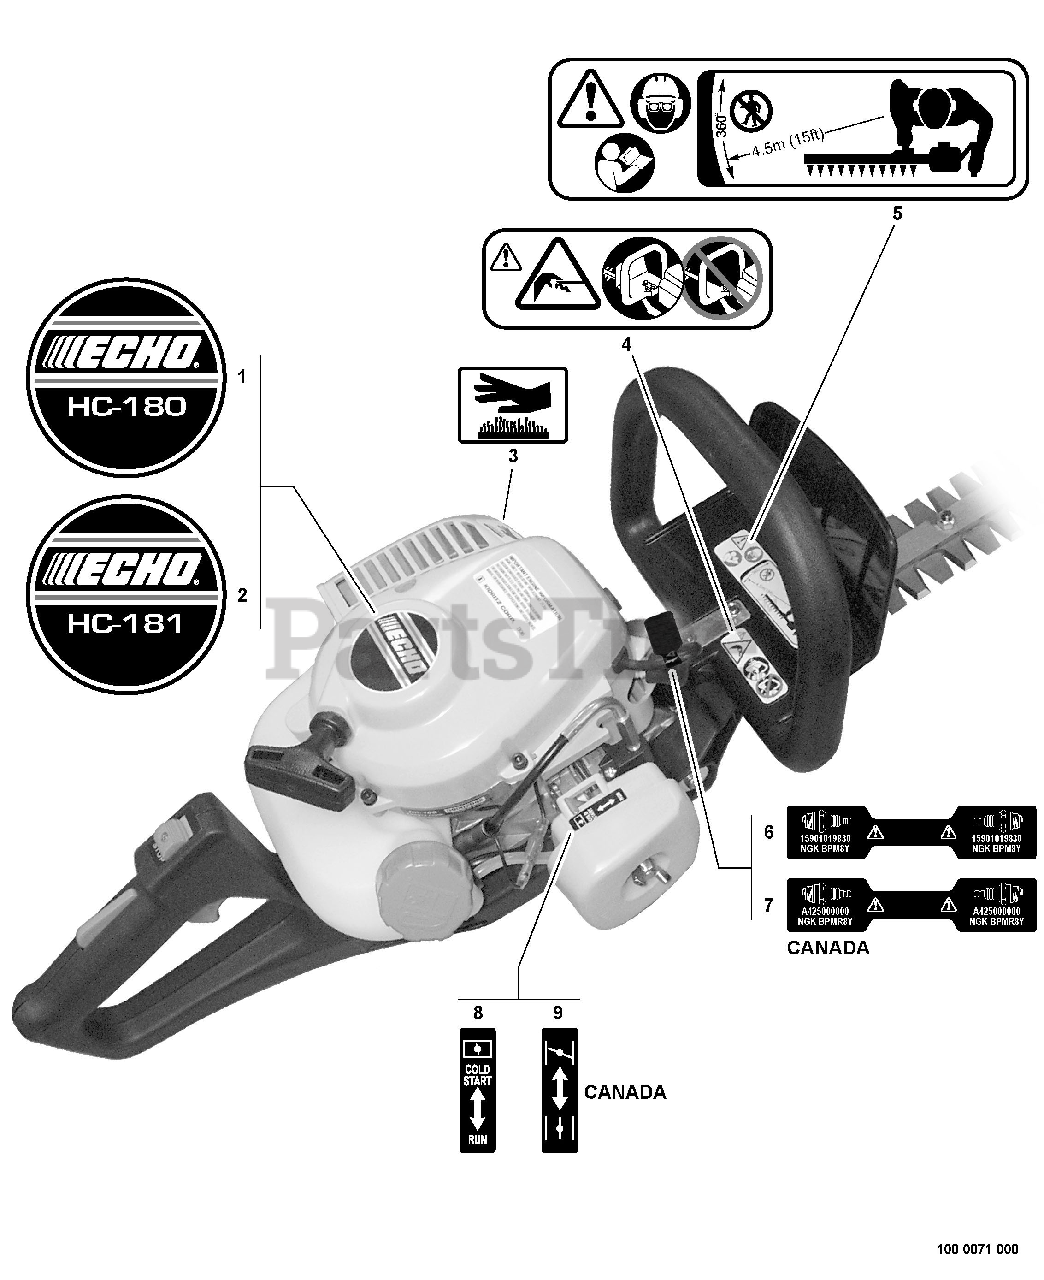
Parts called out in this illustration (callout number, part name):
1	LABEL - MODEL HC-180
2	LABEL - MODEL HC-181
3	LABEL - HOT SURFACE
4	LABEL - CAUTION
5	LABEL - CAUTION
6	LABEL - SPARK PLUG -- BPM-8Y
7	LABEL - SPARK PLUG -- BPMR-8Y
8	LABEL - CHOKE
9	LABEL - CHOKE
